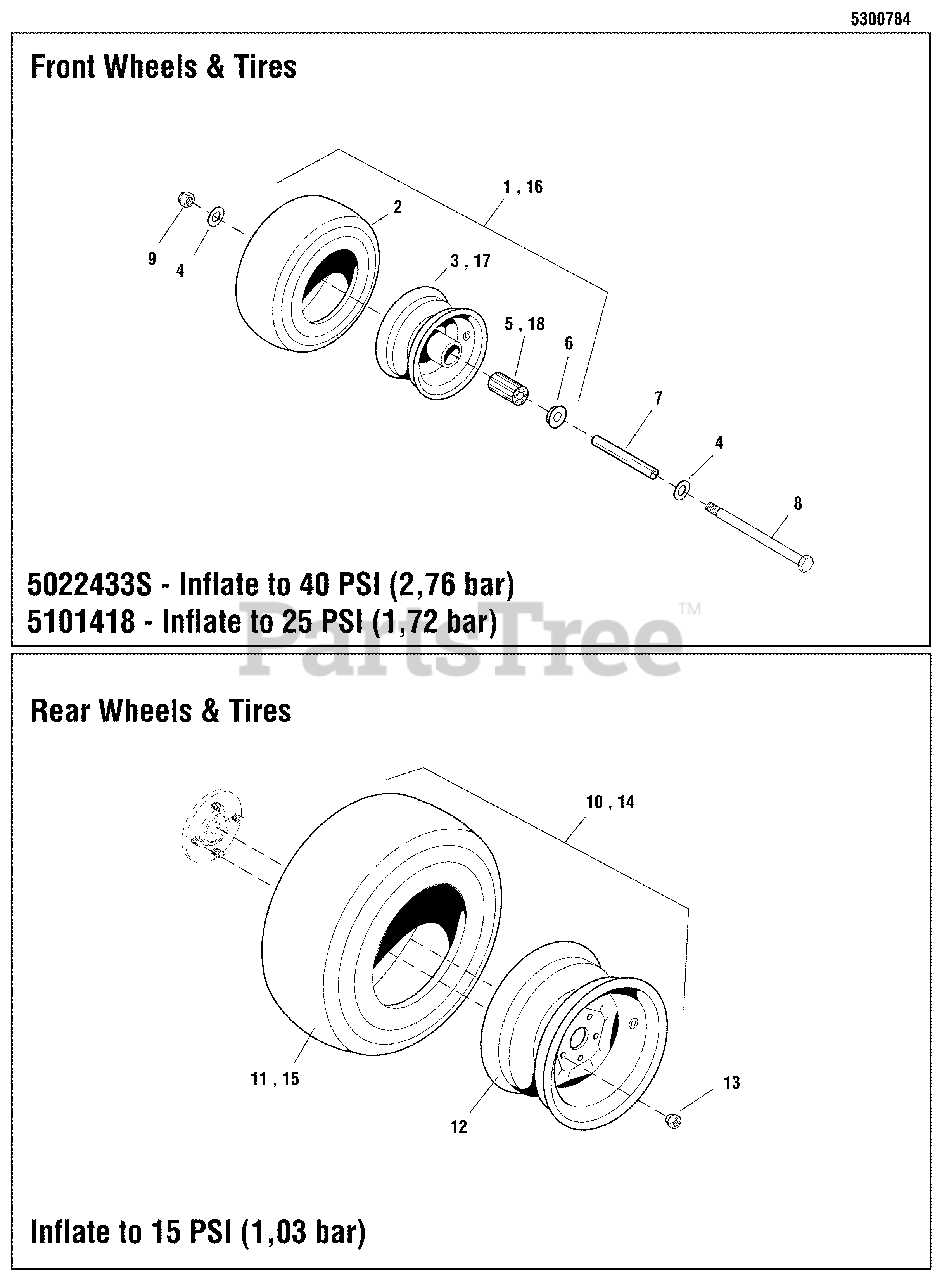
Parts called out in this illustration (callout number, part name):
2	TIRE, FRONT, 11 X 4.0 - 5
3	WHEEL ASSEMBLY, COMPLETE
4	WASHER, 1/2 SAE
5	BEARING, ROLLER
6	BEARING, RETAINER
7	CASTER AXLE DDSH
8	BOLT, 1/2-13 X 7" GD5 YZ
9	NUT, 1/2-13 HEX NYLON LOCK
10	TIRE ASM, REAR, 20 X 8.0 X 10
11	TIRE, REAR, 20 X 8.0 X 10
12	RIM-10X7-5-4.5 SOLID
13	NUT, 1/2-20, FOR WHEEL BOLT SILVER
14	TIRE ASM, REAR, 20 X 10 X 10
15	TIRE, REAR, 20 X 10 X 10
16	WHEEL, CASTER, 11 X 4.0-5
17	WHEEL FOR 11X4.0-5 TIRE ASSM
18	BEARING, CASTER WHEEL, 11 X 4.0-5
